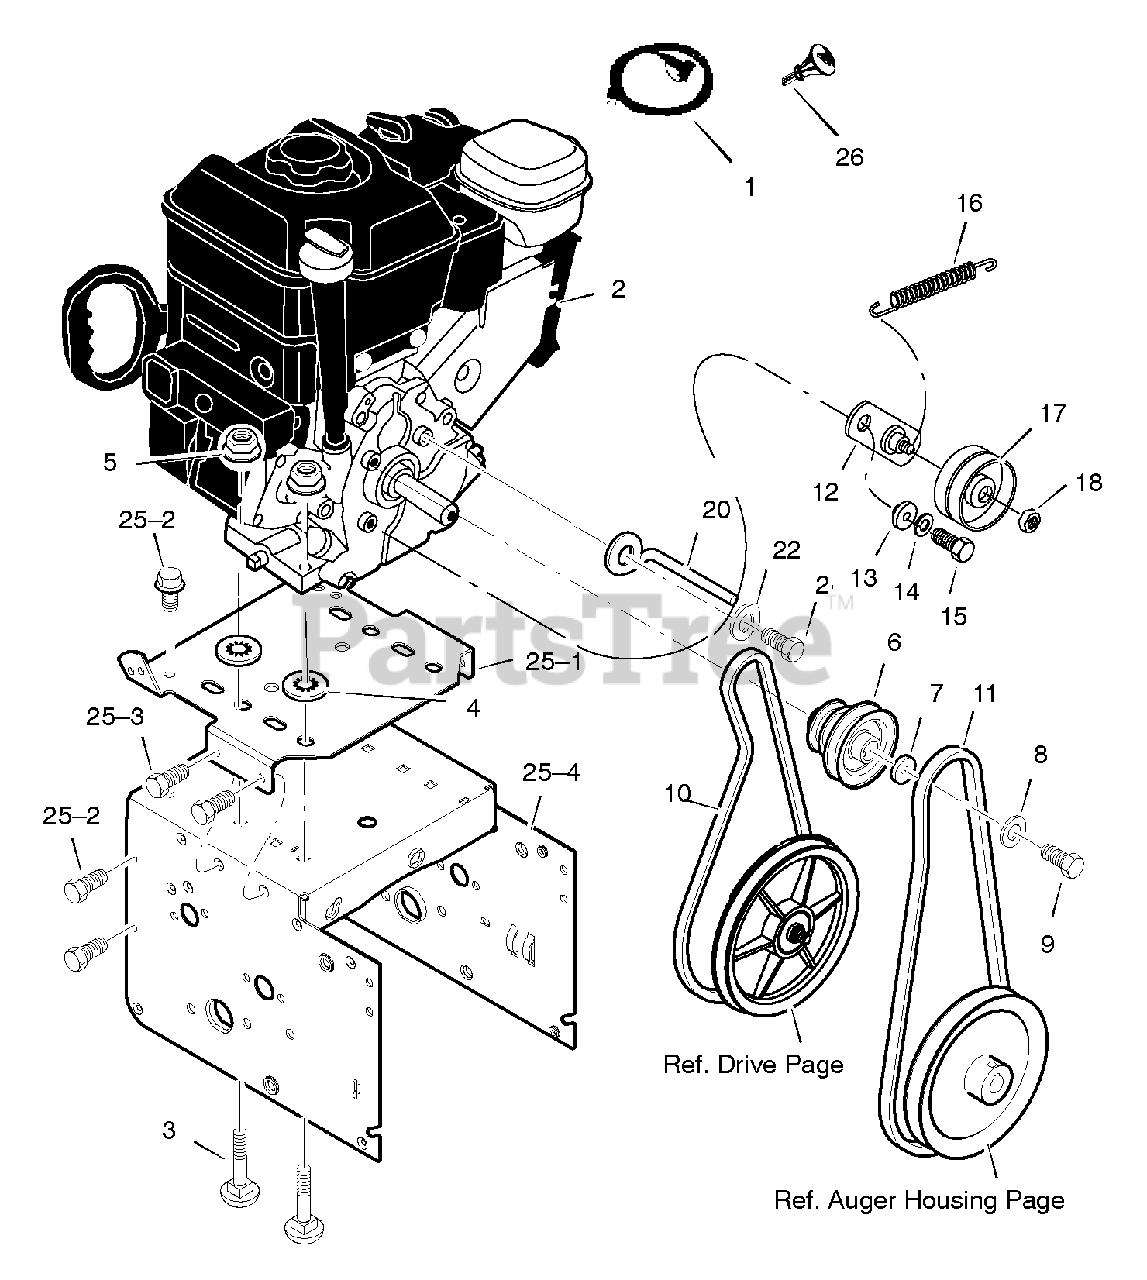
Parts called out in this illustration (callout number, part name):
1	CORD, Electric, 10FT. 110V
2	ENGINE
3	BOLT, CARRIAGE
4	RETAINER, PUSH
6	PULLEY, ENGINE
7	WASHER
8	WASHER
9	SCREW
10	BELT, DRIVE V 3L
11	BELT, AUGER V 4L
12	BRACKET ASSEMBLY, IDLER
13	BUSHING, IDLER BRACKET
14	WASHER, SPLIT
15	SCREW 5/16-24 X 0.75
16	SPRING, IDLER TRACTION DRIVE
17	PULLEY, IDLER
18	NUT, JAM 3/8-16
20	GUIDE, ROD BELT
22	WASHER
25	FRAME ASSEMBLY
25-1	PLATE, ENGINE
25-2	SCREW
26	KEY, ENGINE
